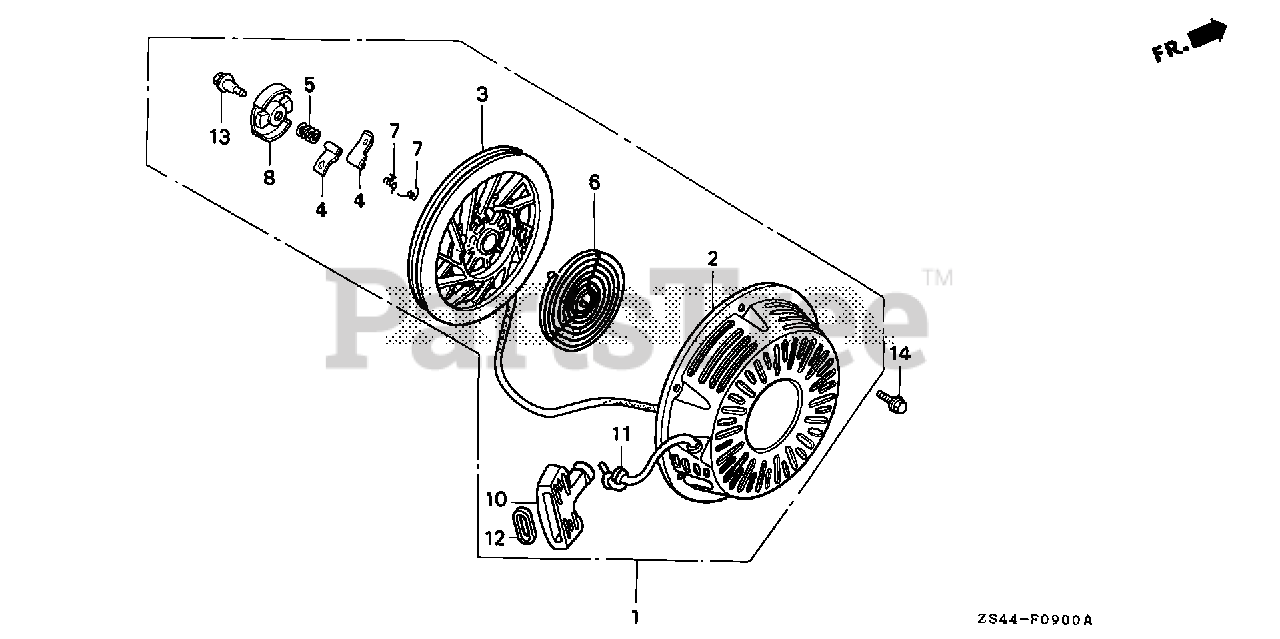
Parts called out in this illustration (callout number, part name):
1	STARTER ASSY., RECOIL *NH1* (BLACK) (ENGINE NO.)
2	CASE, RECOIL STARTER *NH1* (BLACK)
3	PULLEY, RECOIL STARTER
4	RATCHET, STARTER
5	SPRING, FRICTION
6	SPRING, STARTER RETURN
7	SPRING, RATCHET
8	RETAINER, SPRING
10	GRIP, STARTER (ENGINE NO.)
11	ROPE, RECOIL STARTER
12	REINFORCEMENT, GRIP
13	SCREW, CENTER
14	BOLT, FLANGE (6X10)
